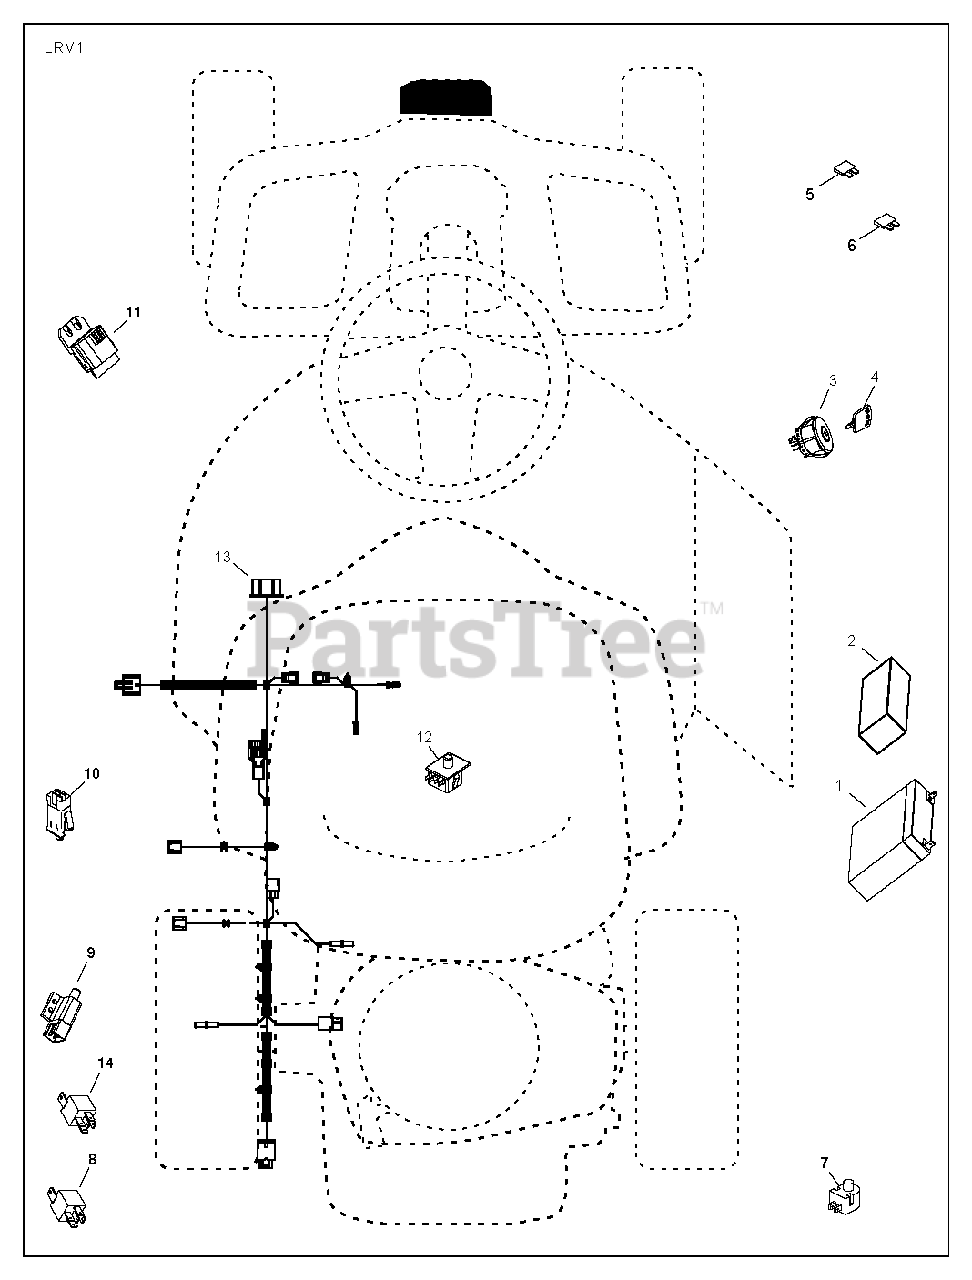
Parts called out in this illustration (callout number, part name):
1	BATTERY.2.8H.LRVA TBR
2	FOAM.POLYURETHANE
3	SWITCH.IGN.DELTA.W.LGH.ROS
4	KEY.CHAIN.BLISTER.PACK.GEN.USA
6	FUSE, 40A
7	PLUNGER SWITCH (COLOR:OLIVE)
8	RELAY, 40A
9	SWITCH INTERLOCKT
10	SWITCH INTERLOOK PUSH-IN
11	MODULE.STARTING.RECOIL.LRV
12	SWITCH.SEAT.DP W/RAMPS
13	HARNESS, IGN, ELECTSTART, LRV
14	RELAY.ASSY.T
